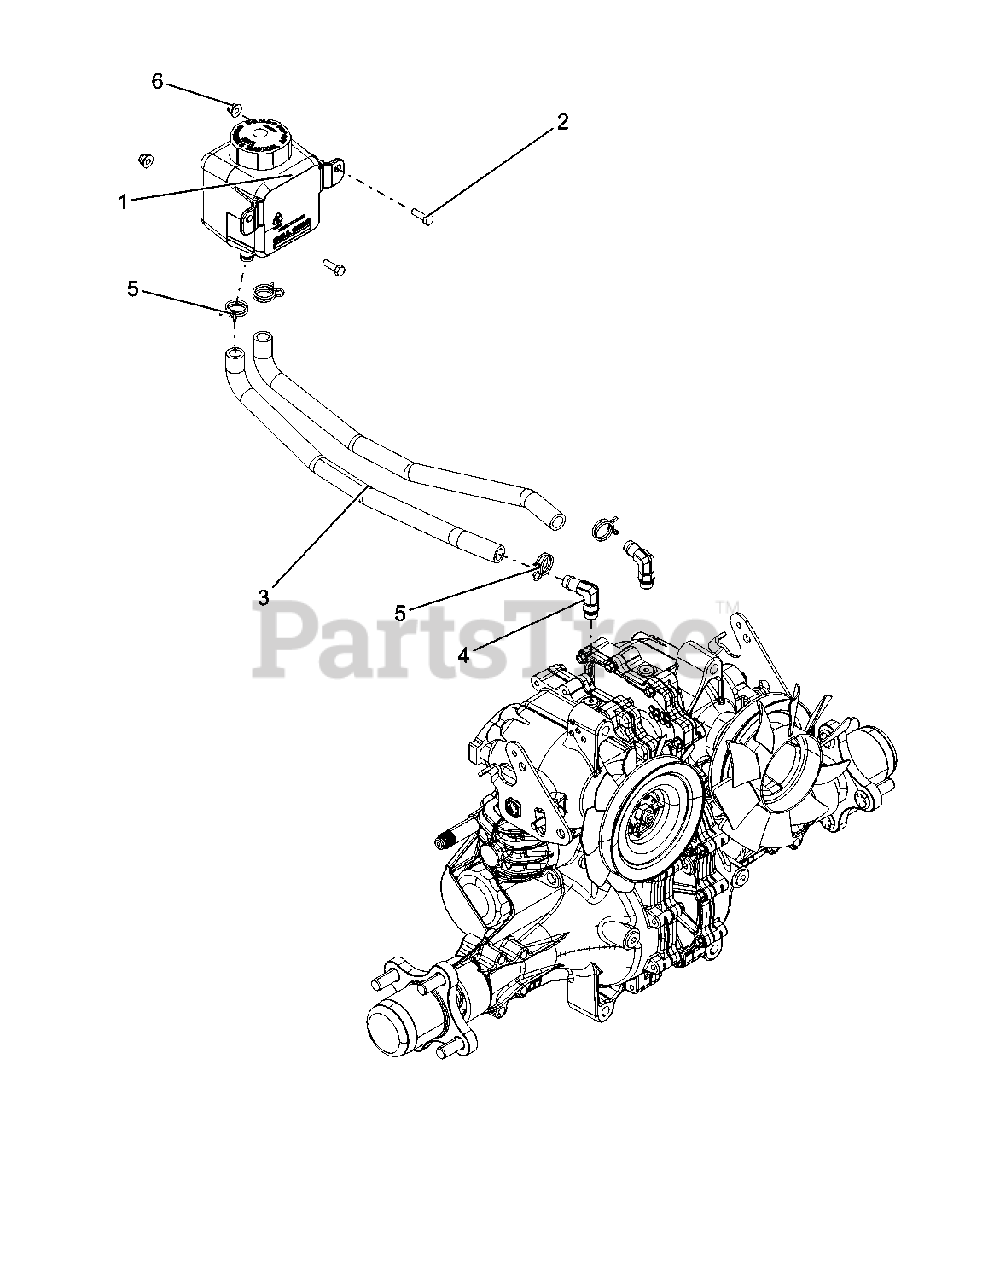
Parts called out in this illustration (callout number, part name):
1	TANK, HYDRO OVERFLOW 700ML
2	BLT, HEX M6-1X20 GR8.8 ZC120
3	HOSE, HYDRO .50" ID X 17.125"
4	FTG, ORB 90° 7/16-20 - 1/2 BARB
5	HOSE CLAMP, DBW 12MM
6	NUT, LK-NYL-FLG M6-1.0 GR8.8 ZC120
